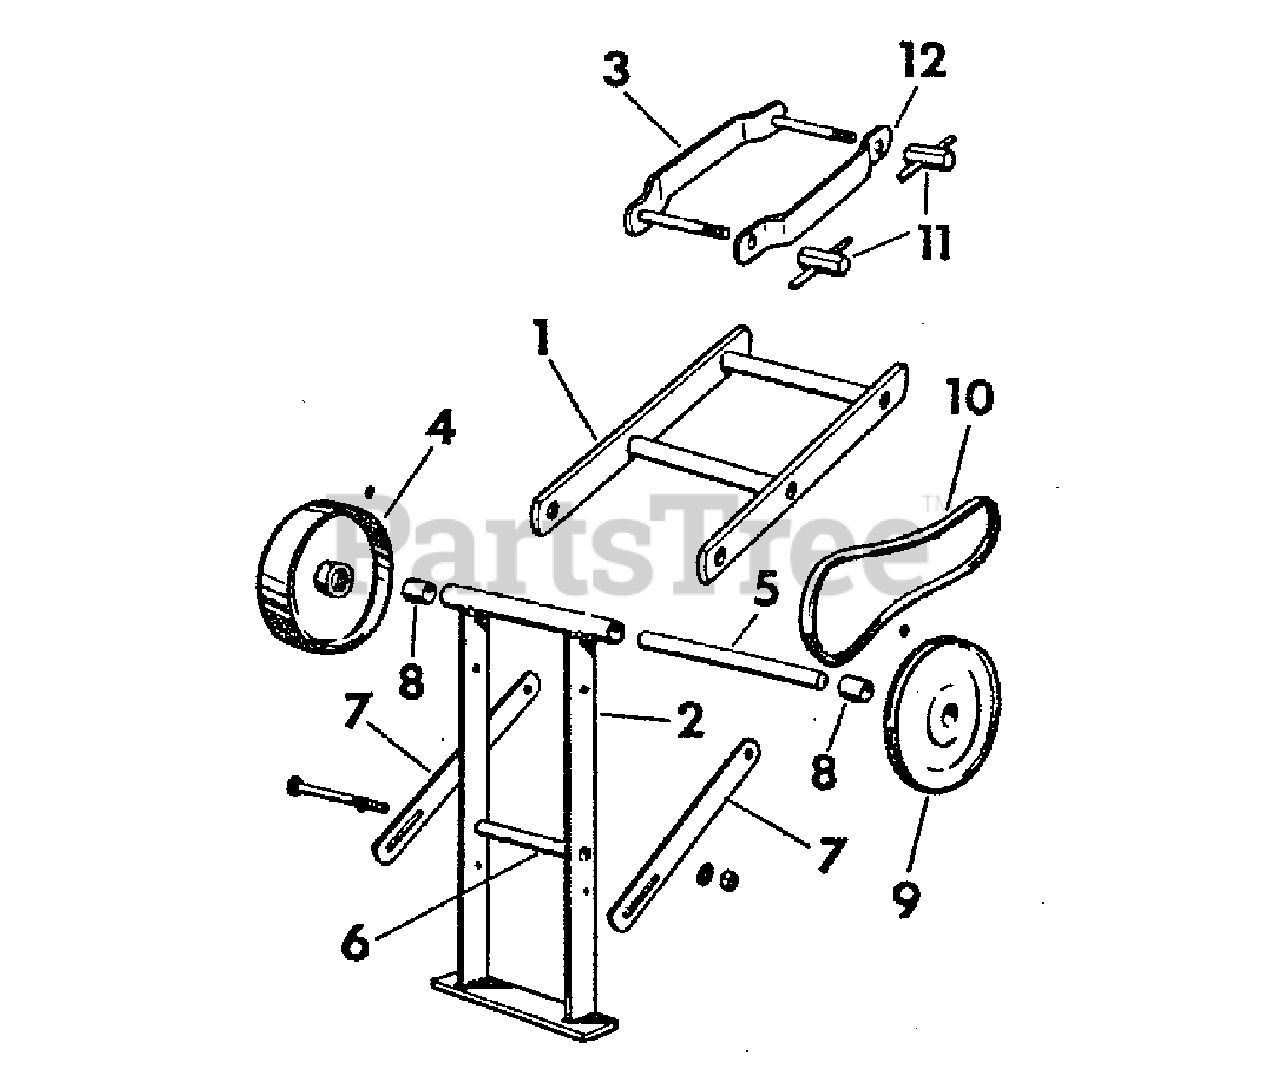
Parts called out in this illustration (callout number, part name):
2	BRACKET, Bearing
3	CLAMP, Hitch
5	COUNTERSHAFT
9	SHEAVE, Transmission
10	BELT, "V"
11	NUT, Wing, Complete
12	SIDE PLATE, Hitch
